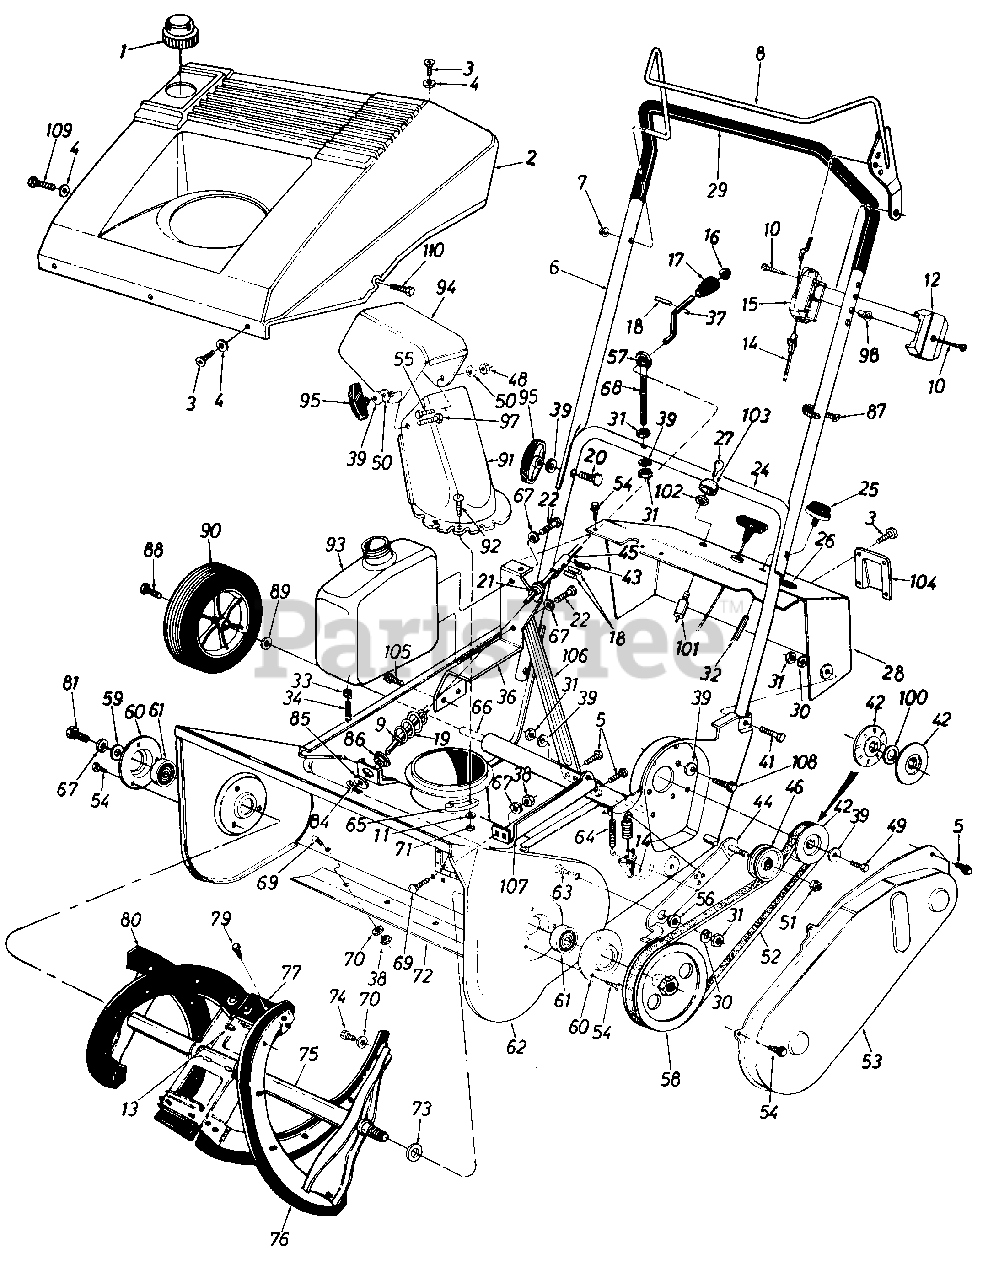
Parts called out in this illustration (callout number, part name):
1	Gas Tank Cap
2	Shroud
3	Hex B-Tap Scr. #10 x .5" Lg.
4	Fl-Wash. .203" I.D. x .41"
5	Hex L-Wash. Hd. AB-Tap l/q x .62" Lg.
8	Control Handle Ass'y. L.H.
9	Fl-Wash. .385" I.D. x .62"
10	Truss Mach. Hi-B Tap Scr. #12 x 1.5" Lg.
11	Fl-Wash. .281" I.D. x .5" O.D.
12	Control Panel Half
13	Pop Rivet .188" Dia.
14	Clutch Cable 35" Lg.
15	Control Panel Half
16	Push Cap 3/8" Rod
17	Knob 3/8" Dia. Hole
18	Roll Pin 1/8" Dia. x .63" Lg.
19	Lower Chute Crank Ass'y.
20	Curved Carriage Bolt 5/16-18 x 1.75" Lg.
21	Chute Crank Grommet
22	Hex Bolt 1/4-20 x .5" Lg.
26	Plastic Plug
30	L-Wash. 5/16" I.D.
31	Hex Nut 5/16-18 Thd.
32	Primer Hose 9" Lg.
33	Hose Clamp 1/2" O.D.
34	Gas Line 16" Lg.
36	Gas Tank Support Brkt.
37	Upper Chute Crank
38	Hex Jam Nut 1/4-20 Thd.
39	Bell-Wash. .345" I.D. x .88"
41	Hex Bolt 5/16-18 x 1.5" Lg.
42	3/8" "V"-Pulley Half .625" I.D. x 6.0" O.D.
43	Hairpin Clip 3/8" Dia.
44	Idler Brake Brkt. Ass'y.
45	Spacer .38" I.D. x 1.12" Lg.
46	Fl-Idler w/Flanges 2.12" O.D.
48	Hex L-Nut 5/16-18 Thd.
49	Hex Bolt 5/16-24 x .75" Lg.
50	Fl-Wash. .344" I.D. x 1.25"
51	Hex Patch L-Nut 3/8-24 Thd.
52	"V"-Belt
54	Hex B-Tap Scr. 1/4" x .38" Lg.
55	Carriage Bolt 5/16-18 x .75"
56	Shld. Spacer .50" Dia. x .27"
57	Plastic Bushing .38" I.D.
58	1/2" "V"-Pulley 1/2-20 L.H. x 6"
59	Fl-Wash. 1/4" I.D. x .93" O.D.
64	Extension Spring 1.12" Lg.
65	Chute Flange Keeper
66	Wheel Axle 20.6" Lg.
67	L-Wash. 1/4" I.D.
68	Eyebolt
69	Carriage Bolt 1/4-20 x .50"
70	Fl-Wash. .281 I.D. x .73"
71	Hex L-Nut 1/4-20 Thd.
72	Shave Plate
73	Fl-Wash. .510" I.D. x 1.0" O.D.
74	Hex Wash. B-Tap Scr. 1/4 x .62"
76	Rubber Spiral L.H.
77	Rubber Paddle
79	Hex Wash. B-Tap Scr. #10 x .62" Lg.
80	Rubber Spiral R.H.
81	Hex Wash. TT-Tap Cl-Scr. 1/4-20 x .75" Lg.
84	Cotter Pin 3/32" Dia. x .75"
85	Fl-Wash. .406" I.D. x 1.25"
86	Hex Bushing .385" I.D.
87	Cable Tie
88	Hex Tap Scr. 3/8-24 x .88" Lg.
89	Fl-Wash. .510" I.D. x .75"
90	7" Wheel & Tire Ass'y.
91	Lower Chute
92	Truss Mach. Scr. 1/4-20 x .75"
93	Fuel Tank Two Qt.
94	Upper Chute
95	Knob Handle Ass'y.
97	Carriage Bolt 5/16-18 x 1"
98	Control Disc Pin
100	Fl-Wash. .635" I.D. x .93" O.D. x .06"
101	Key Switch
102	Ignition Switch Nut 5/8-32 Thd.
103	Ignition Switch Cap
104	Choke Cover
105	Hex Wash. Hd. Tap Scr. 1/4-.5"
108	Hex Bolt 5/16-18 x 5/8" Lg.
109	Pan Hd. Tap Scr. #10 x 1.25" Lg.
110	Hex Wash. Hd. Tap Scr. 1/4 -20 x 1 " Lg.
